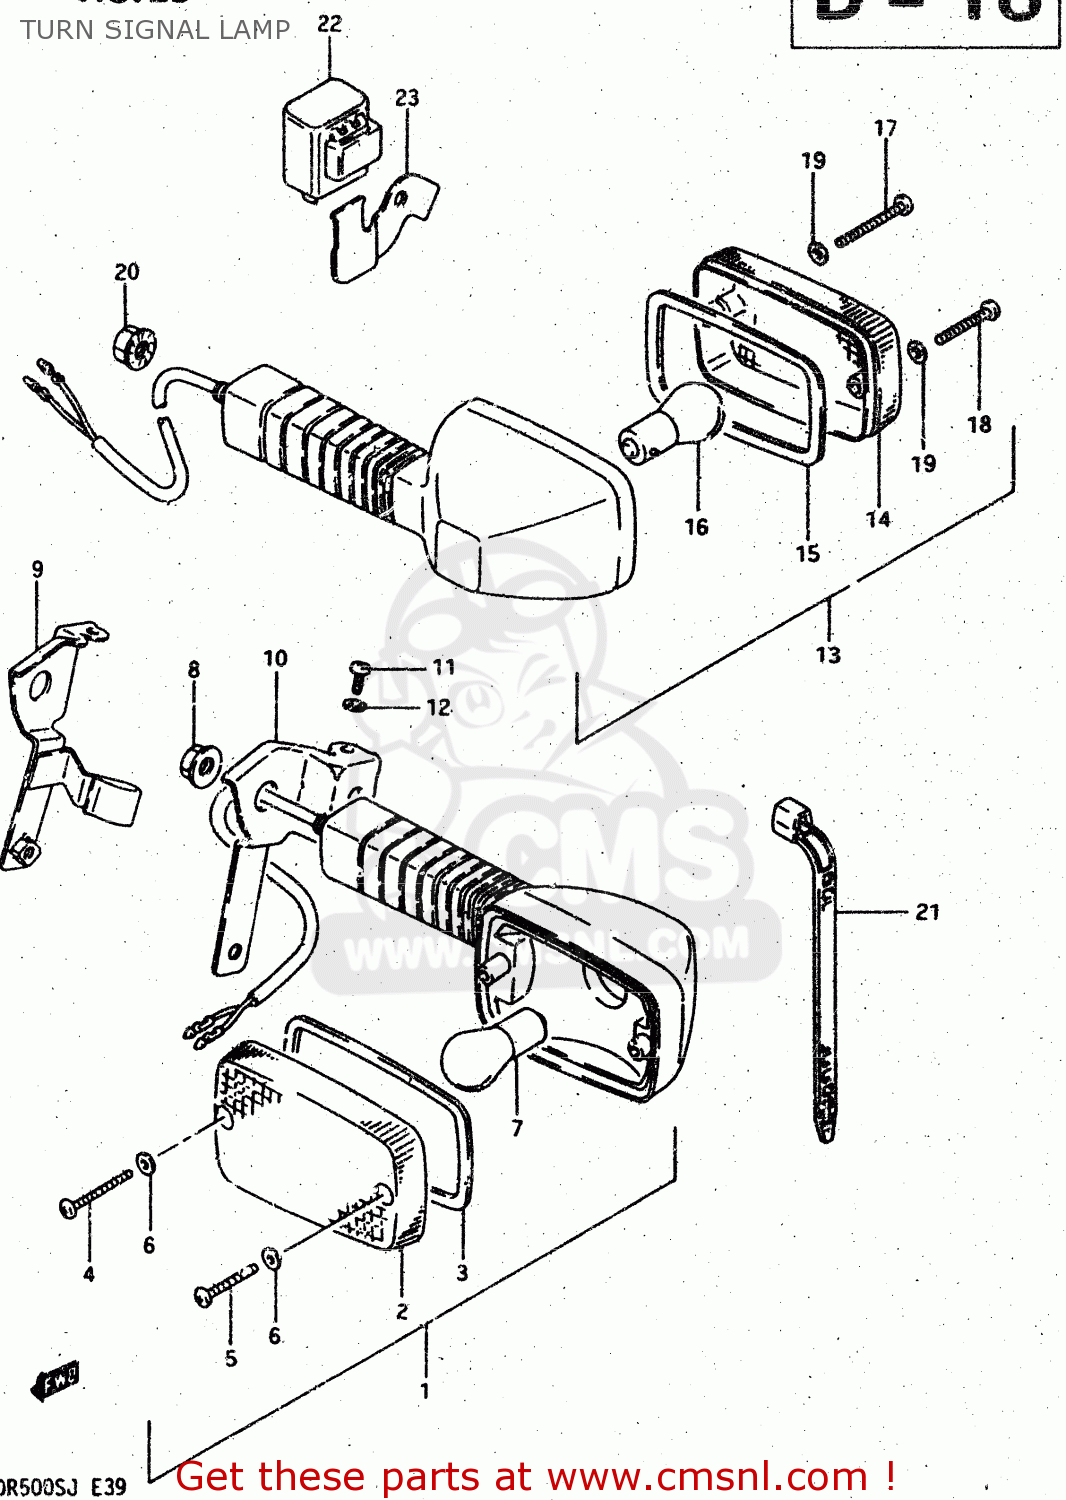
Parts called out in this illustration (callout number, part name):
1	LAMP ASSEMBLY,FRONT TURN SIGNAL
2	LENS,FR
3	GASKET (NAS)
4	SCREW,TURN SIG LENS FITTING
5	SCREW
6	GASKET (NAS)
7	BULB (12V,21W)
8	NUT
9	BRACKET,FRONT TURN SIGNAL
10	BRACKET,FRONT TURN SIGNAL
11	SCREW
12	WASHER,LOCK
13	LAMP ASSY,RR
14	LENS,RR
15	GASKET (NAS)
16	BULB(12V21W)
17	SCREW,TURN SIG LENS FITTING
18	SCREW
19	GASKET (NAS)
20	NUT
21	CLAMP(L:125)
22	RELAY ASSEMBLY,TURN SIGNAL
23	BRACKET,TURN SIGNAL RELAY
